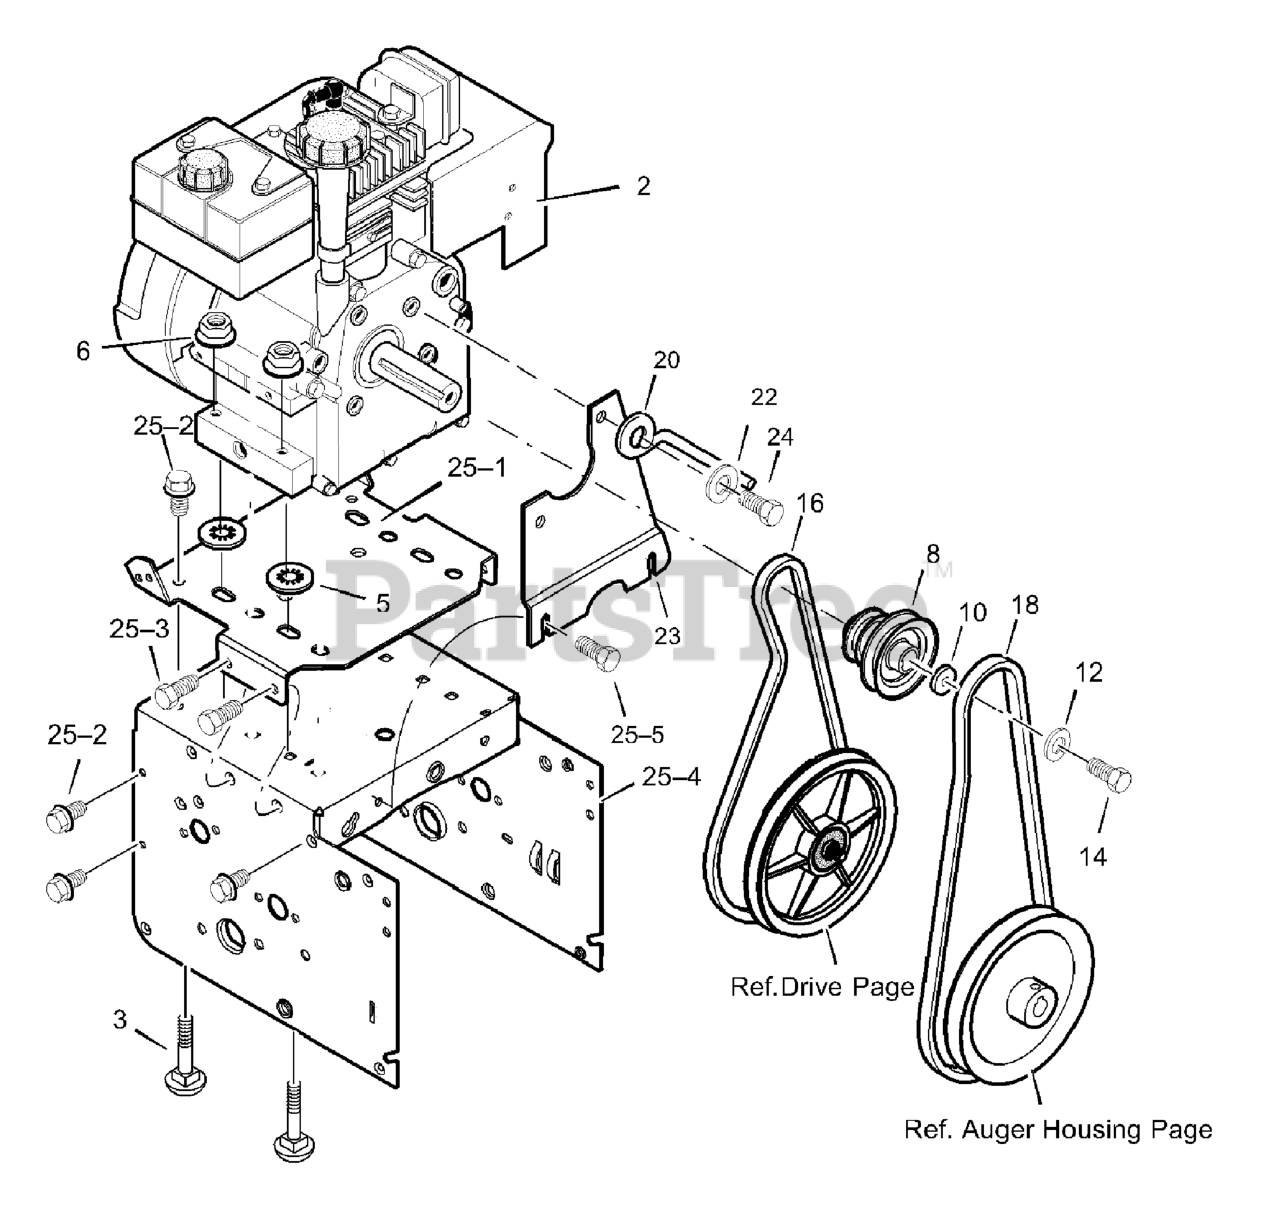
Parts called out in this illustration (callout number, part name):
2	ENGINE, Tecumseh *
3	BOLT, CARRIAGE 5/16-18
5	RETAINER, PUSH
6	NUT 5/16-18
8	PULLEY, ENGINE
10	WASHER
12	WASHER, HVSPTLK .38ID
14	SCREW, 3/8-24 x 1.00
16	BELT, V 3L 33.16LG
18	BELT, V 4L 38.1
20	GUIDE, ROD BELT
22	WASHER, SPTLK .31X.58X.08
23	PLATE, ANTI VIBRATION
24	SCREW, 5/16-24 x 1.00
25	FRAME ASSEMBLY
25-1	PLATE, ENGINE MOUNT
25-2	SCREW 1/4-20 X .63
25-3	SCREW 5/16-18 X .50
25-4	FRAME, MOTOR BOX
